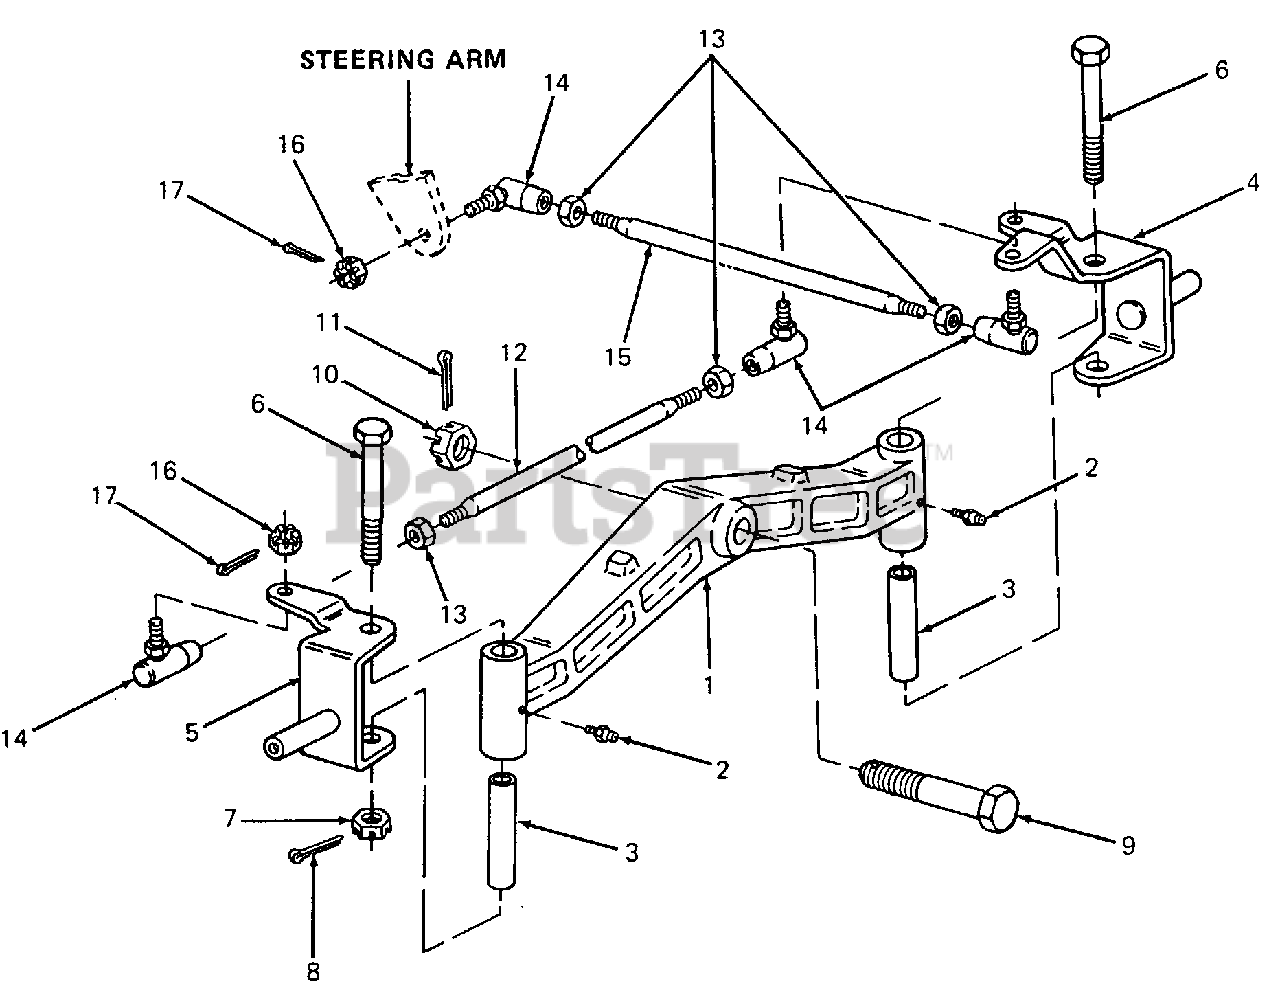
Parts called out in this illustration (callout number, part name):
3	Spacer, Steering Knuckle
6	Bolt, Hex, 1/2-20 X 5.25 Lg GR5
7	Nut, Hex Castle, 1/2-20 GR5
8	Pin, Cotter, 3/32 Dia X 1.0 Lg
9	Bolt, Hex, 3/4-10 X 5.25 Lg GR5
10	Nut, Hex Castle, 3/4-10 GR5
11	Pin, Cotter, 1/8 Dia X 1.5 Lg
13	Nut, Hex Jam, 3/8-24 GR5
14	Ball Joint
15	Link, Drag
16	Nut, Hex Castle, 3/8-24 GR5
17	Pin, Cotter, 3/32 Dia X .75 Lg
